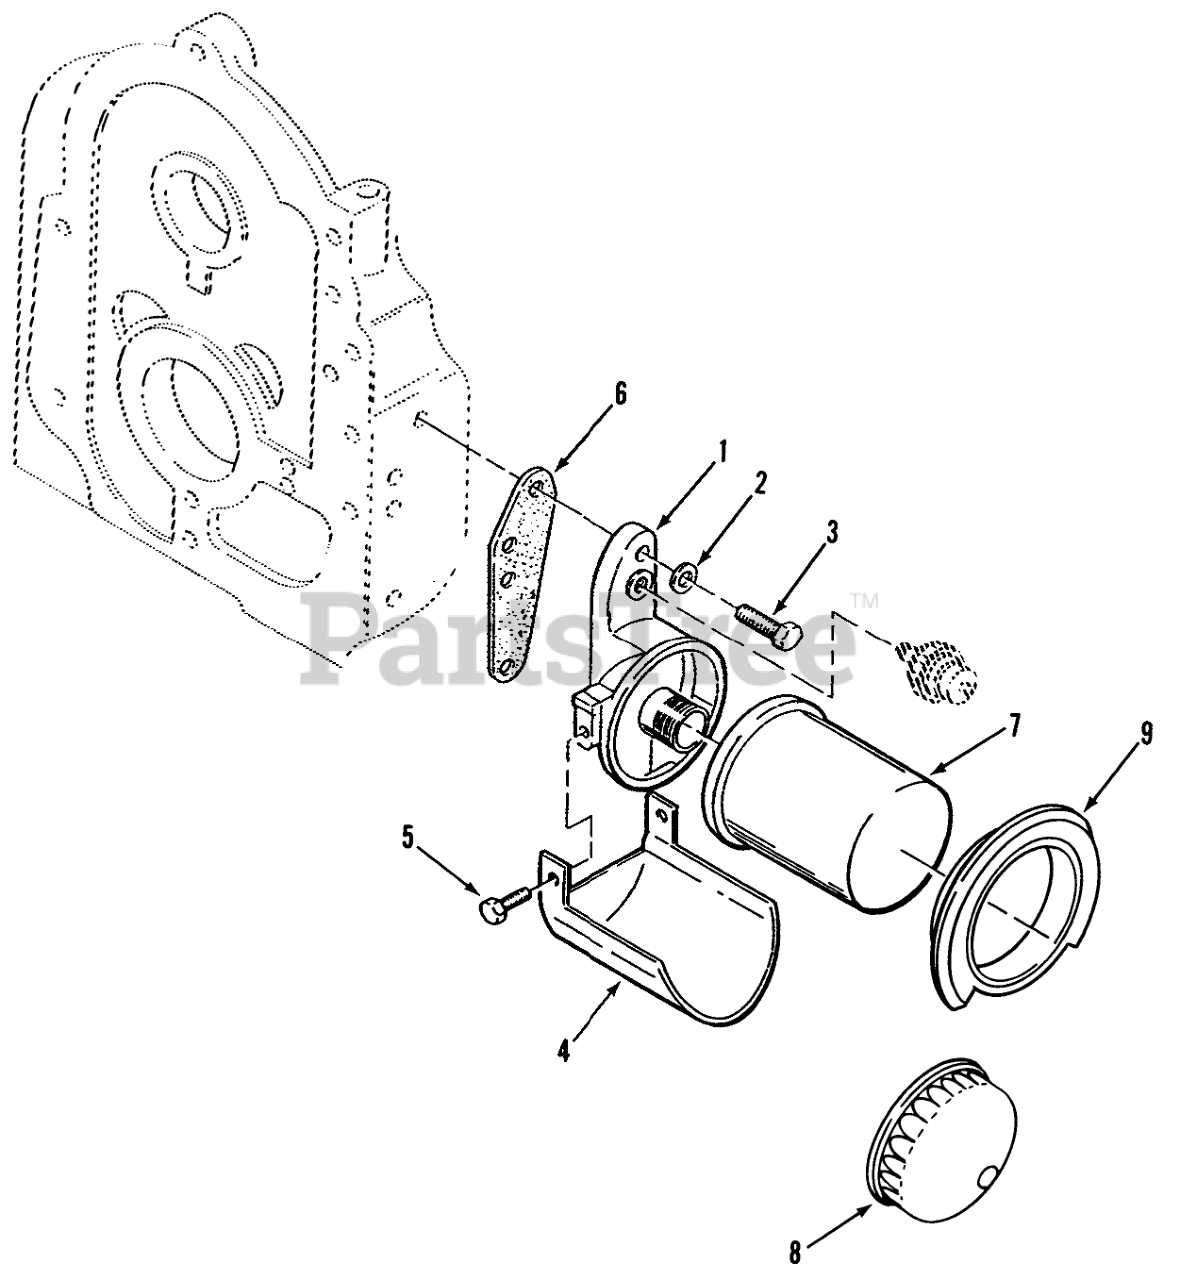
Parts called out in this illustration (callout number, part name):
1	Adapter
2	Washer
3	HHCS 5/16-18 X 1
4	Oil Filter Drain
5	Bolt
6	Gasket
7	Oil Filter
8	Wrench
9	Gasket
